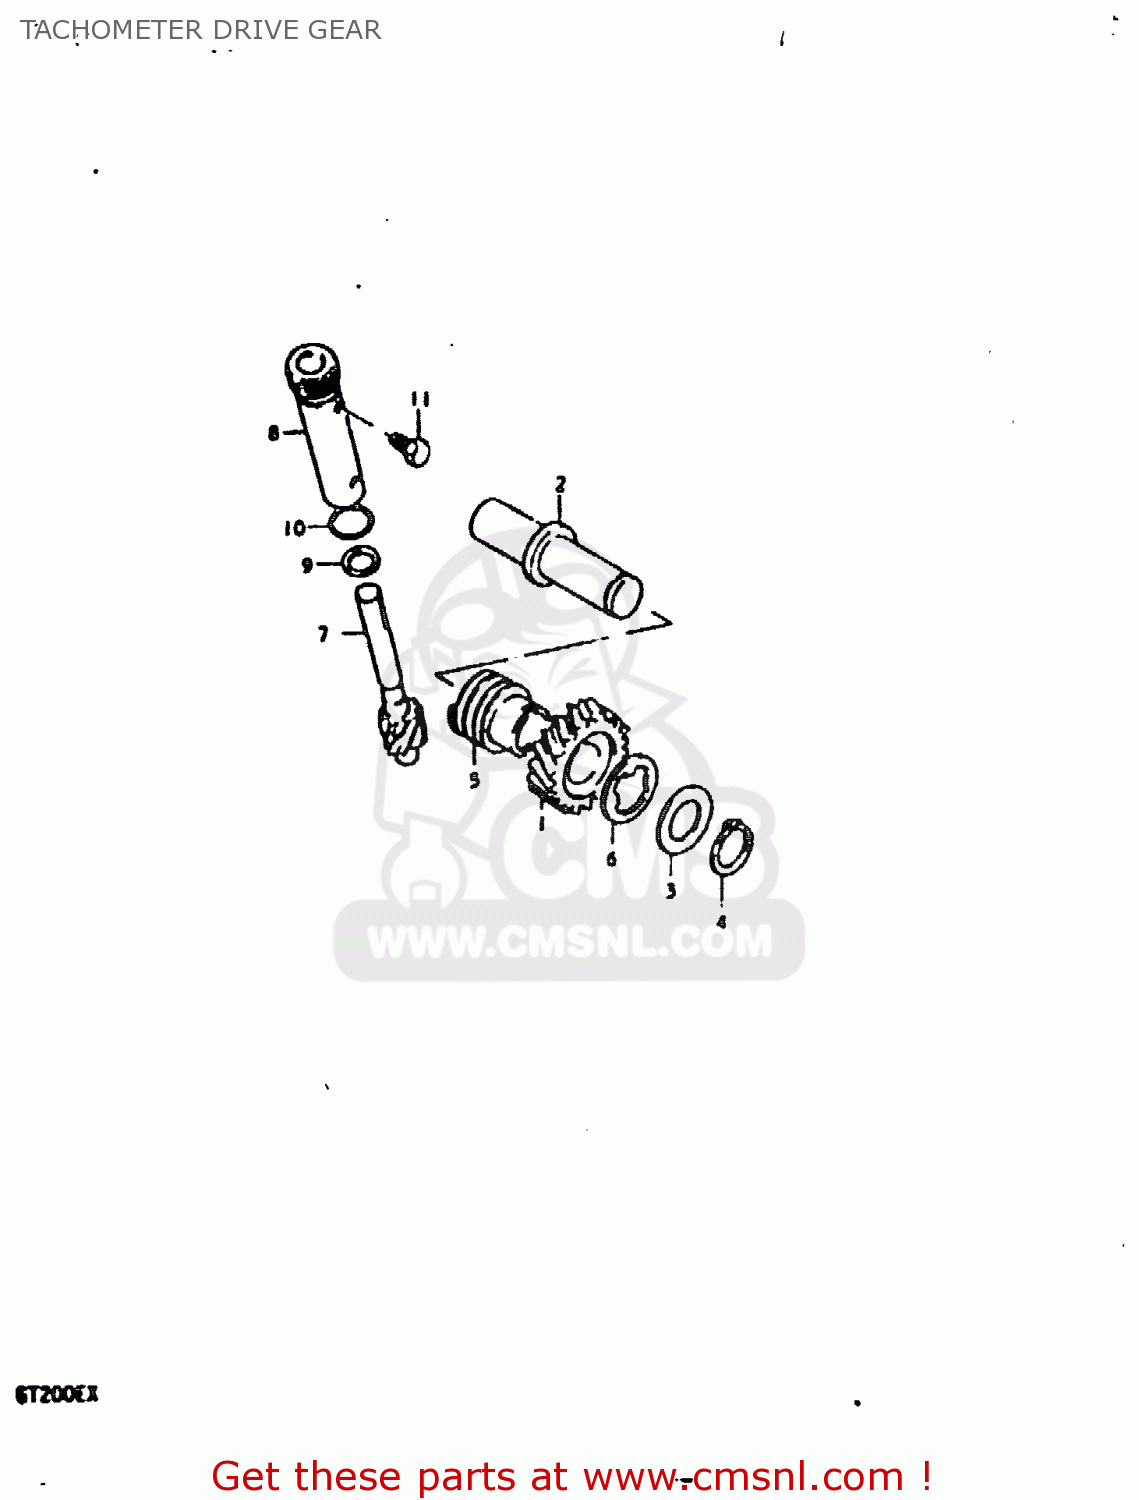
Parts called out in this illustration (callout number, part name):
1	GEAR, TACHOMETER DRIVE NO.2
2	SHAFT,TACHOMETER DRIVEN GEAR
3	WASHER,THRUST
4	CIRCLIP
5	GEAR,TACH DRIVE NO.2(NT:3)
6	RETAINER,TACH DRIVEN GEAR NO1
7	GEAR, TACHOMETER DRIVER
8	SLEEVE,TACHOMETER DRIVE GEAR
9	WASHER(8X13.7X1)
10	O RING
11	BOLT
